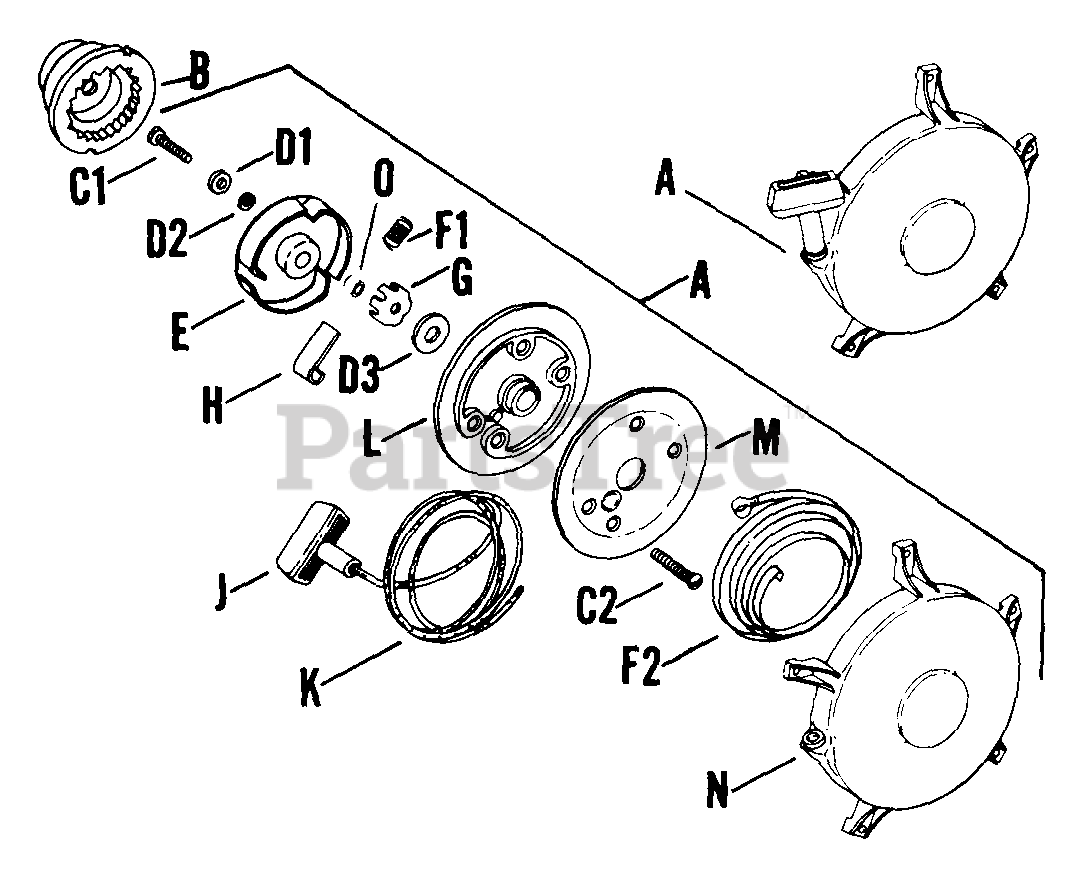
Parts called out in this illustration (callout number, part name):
A	STARTER - USE 47 165 01
B	CUP - DISCONTINUED
D1	WASHER - DISCONTINUED
E	RETAINER
F1	SPRING - DISCONTINUED
H	DOGS - DISCONTINUED
J	HANDLE - USE 25 166 01
N	HOUSING - DISCONTINUED
